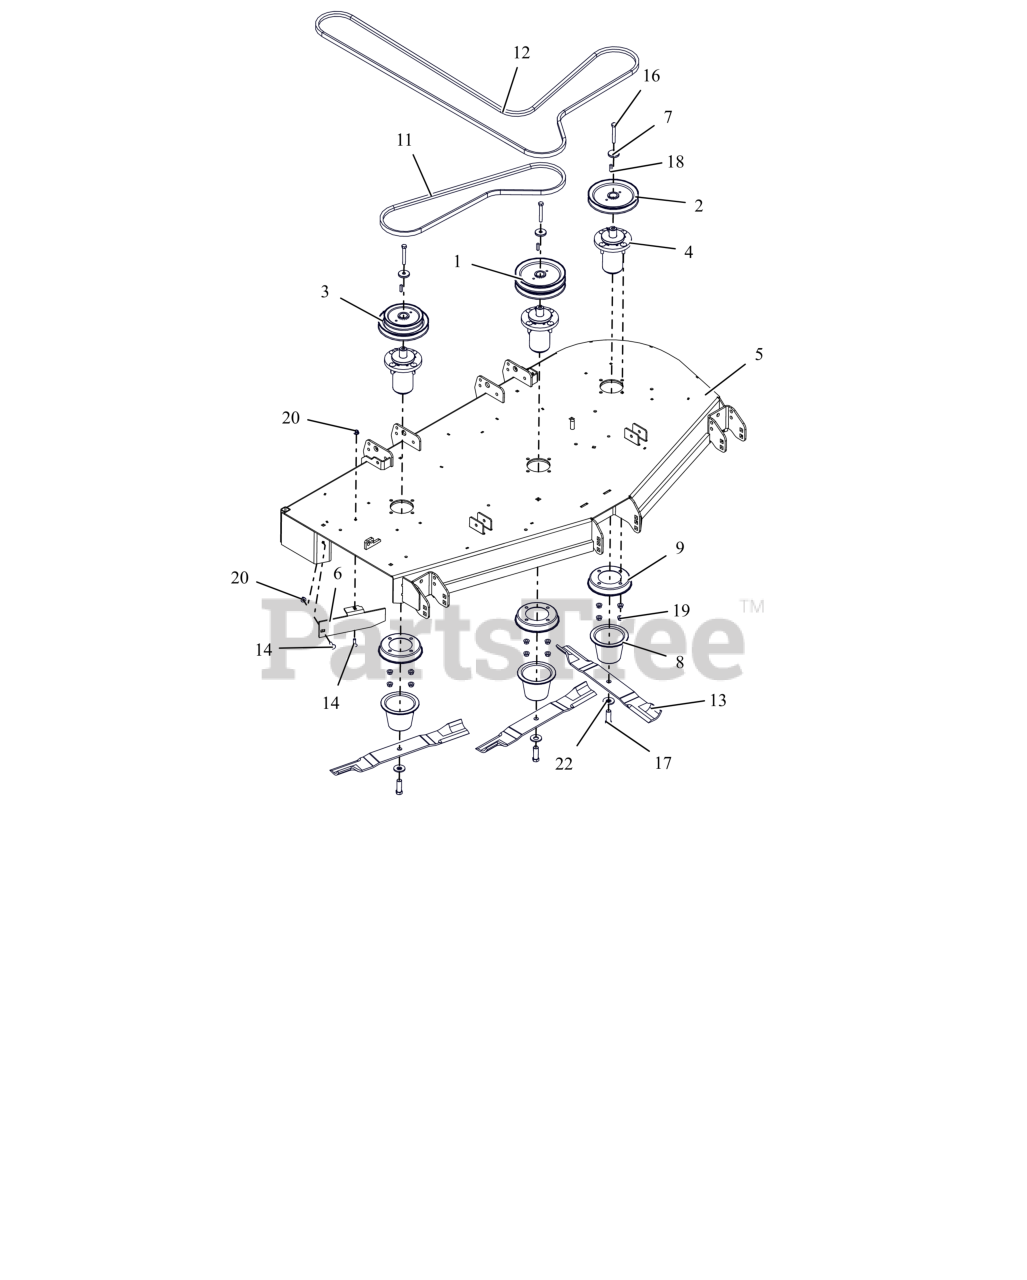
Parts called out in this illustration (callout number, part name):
1	PULLEY, DOUBLE-1"ID X 6.75"OD
2	PULLEY, V-1" ID X 6.75" OD
3	PULLEY, DBL-1"IDX6.75"&5.25"OD
4	ASM, MAINT FREE ALUM SPINDLE
5	WLDMT, PT160 SIDE DISCH DECK (RED)
6	60" DISCHARGE BAFFLE - RED
7	RETAINER, SHEAVE
8	GUARD, SPINDLE LOWER
9	GUARD, SPINDLE TOP
11	V-BELT, B-COGGED
12	BELT, B-SECTION EPDM RAW EDGE
13	BLADE, MOWER (20.50")
14	BLT,RHSN .31-18X1.00 G5 ZCC
16	BLT, HEX .38-16X2.75 G8 ZCC
17	BLT, HEX .62-18X1.75 G8 ZCC
18	KEY, SQ .25X.25X1.00 RC 40-50
19	NUT-LK-CTR-FLG .375-16 GF ZCC
20	NUT,NYL-FLG .31-18 GF ZCC
22	WSHR-BLVL .669X1.535X.138
